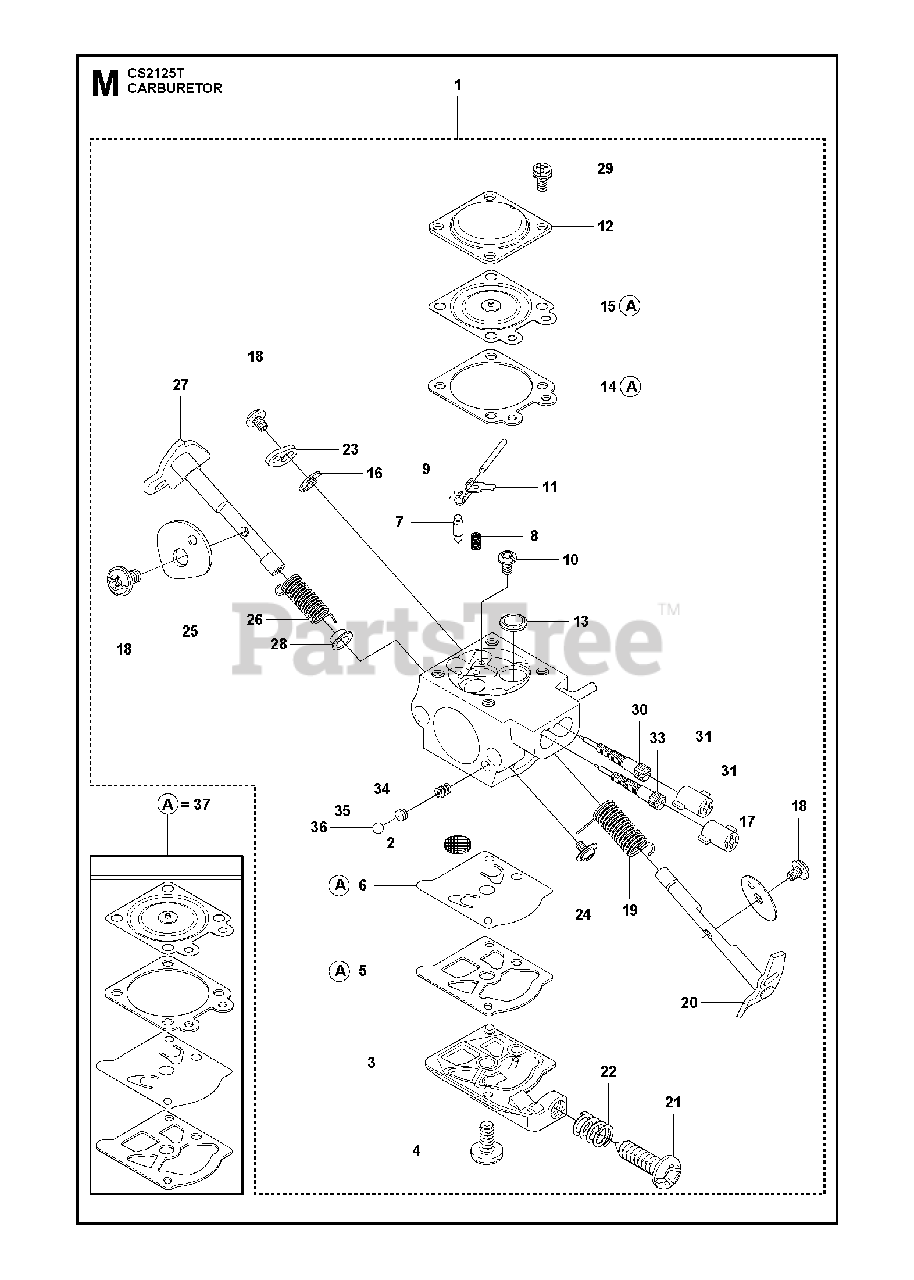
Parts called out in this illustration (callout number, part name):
2	SCREEN
5	GASKET
7	RP VALVE INLET
11	LEVER
14	GASKET METERING
15	DIAPHRAGM
16	E-RING
19	SPRING RETURN
34	SPRING
